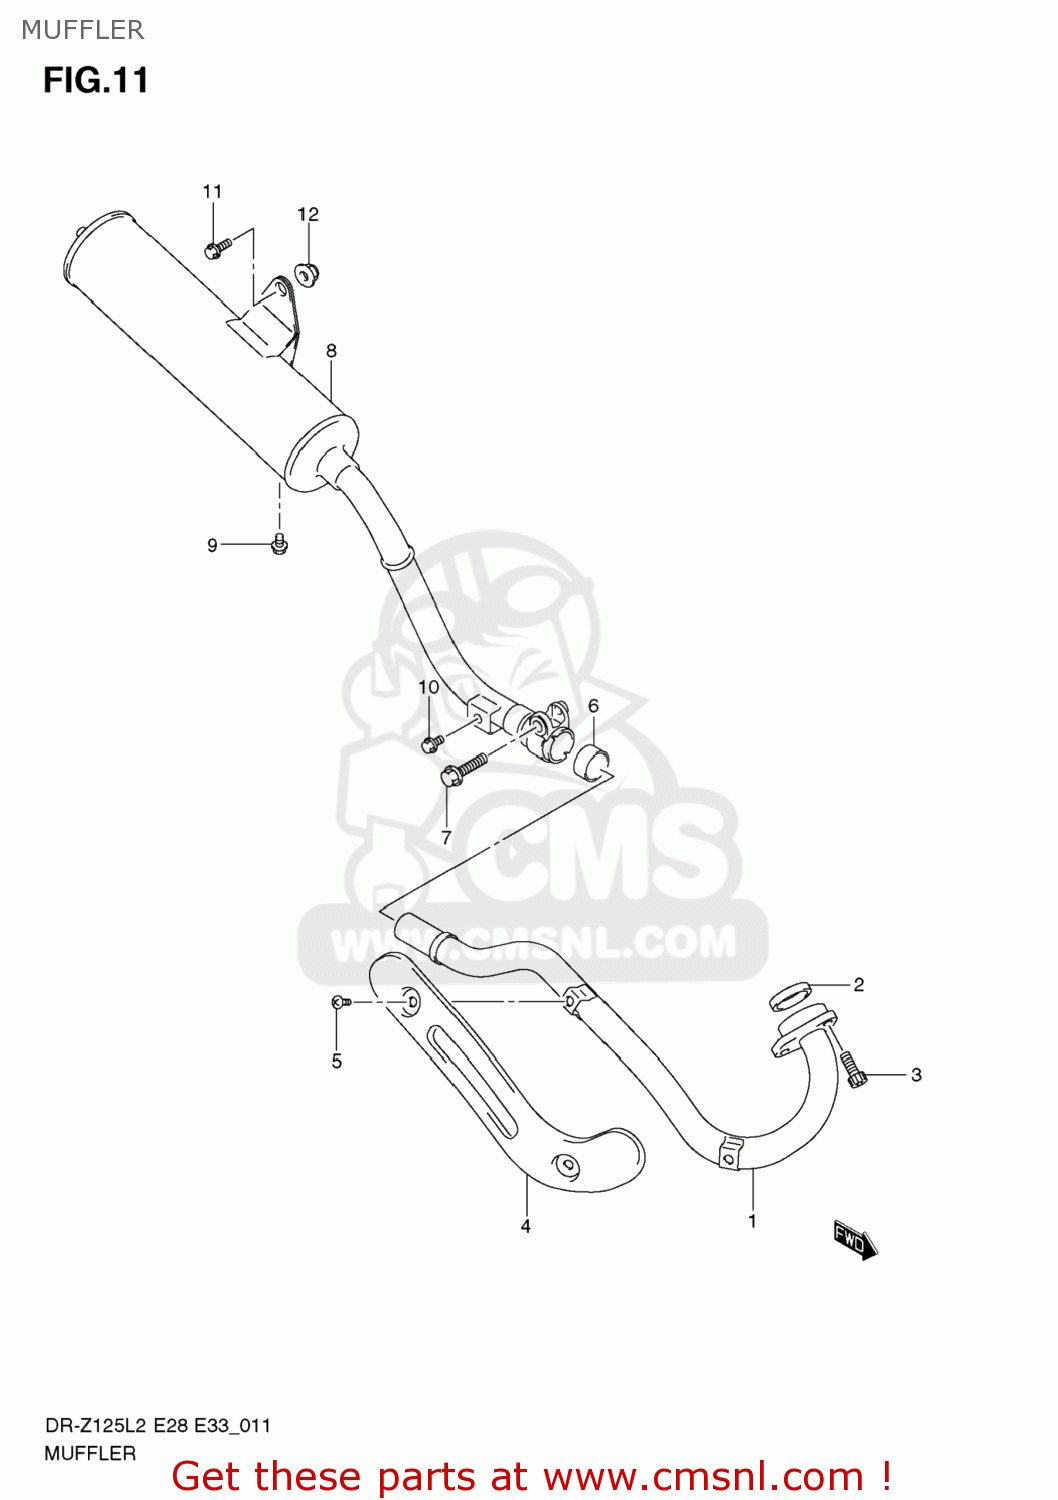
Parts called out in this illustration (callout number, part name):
1	PIPE,EXHAUST
2	GASKET (NAS)
3	BOLT
4	COVER,EXHAUST PIPE
5	SCREW(6X10)
6	CONNECTOR,MUFFLER
7	BOLT
8	BODY,MUFFLER
9	BOLT
10	BOLT
11	BOLT(8X23)
12	NUT
